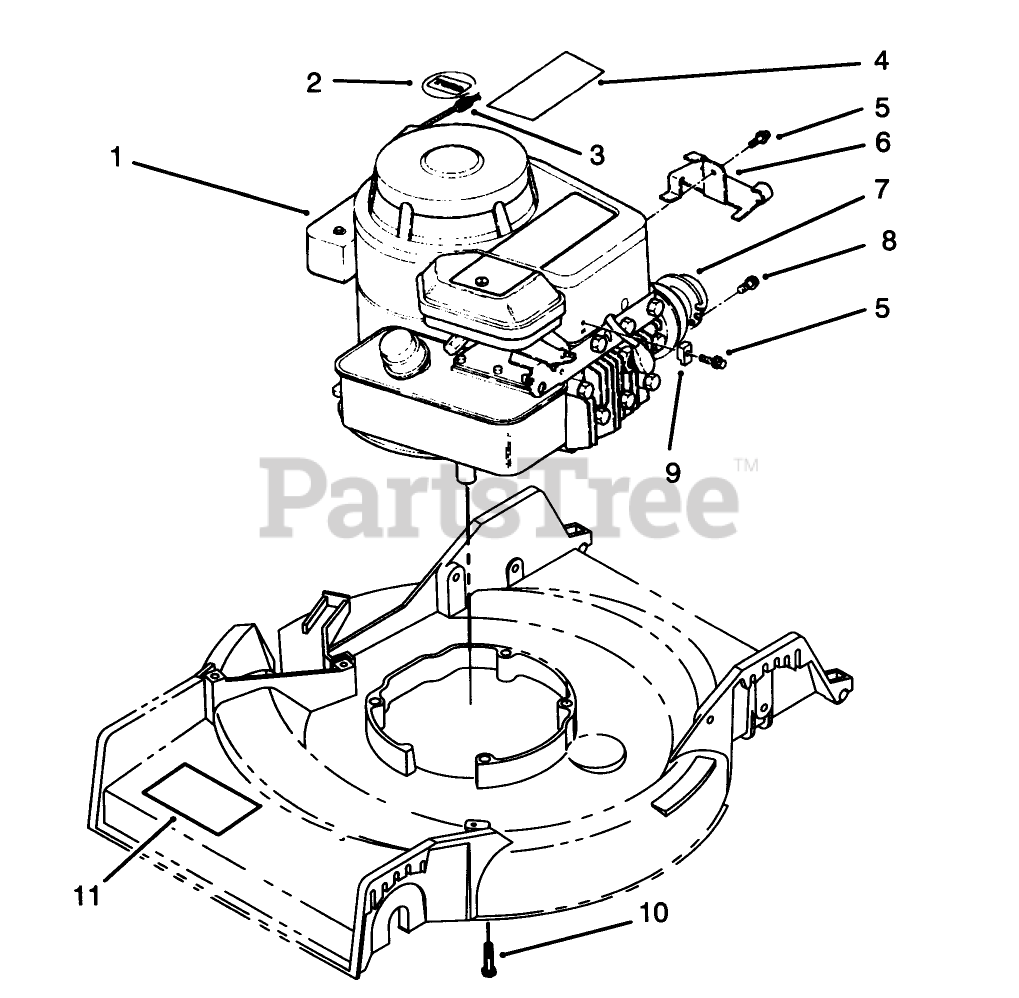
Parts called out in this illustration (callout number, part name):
1	Engine
3	STOP-ROPE
5	CLAMP SCREW F/W ENGINE
6	CABLE BRACKET *
9	CASING CLAMP F/W ENGINE
10	THD FORM SCREW
11	DECAL
